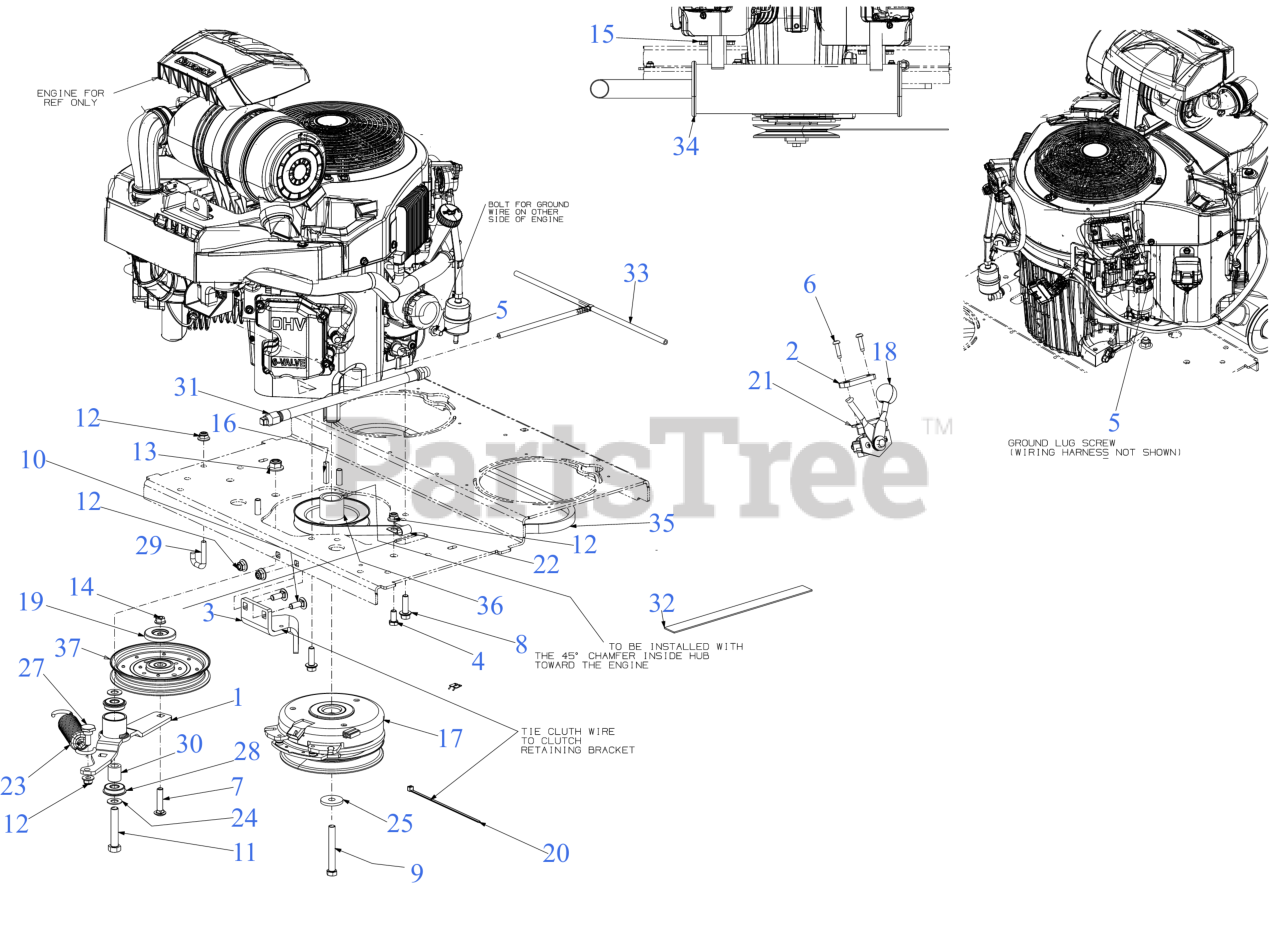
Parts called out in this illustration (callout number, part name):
1	TRANSMISSION IDLER BRACKET
3	CLUTCH RETAINER BRACKET
4	HEX SCREW 3/8-16 x .75
5	SCREW M8 x 1.25 x 16MM GR8.8
6	SCREW 1/4-20 x 1.0
7	CARRIAGE BOLT 3/8-16 x 1.75 GR5
8	SCREW 3/8-16 x 1.25 GR5
9	SCREW 7/16-20 x 3.25 GR5
10	CARRIAGE BOLT 3/8-16 x 1.00 GR5
11	SCREW 1/2-13 x 2.75 GR5
14	HEX LOCK NUT
15	HEX FLANGE NUT
16	SQUARE KEY 1/4 x 1.50
17	ELECTRIC PTO CLUTCH
19	PULLEY CAP
20	7" CABLE TIE
21	ELECTRONIC THROTTLE CONTROL
22	J TYPE CLIP
23	EXTENSION SPRING W/HOOK
24	FLAT WASHER .510 x .995
25	FLAT WASHER .45 x 1.5 x .172 HT
27	SHOULDER SCREW .625 x .302 x 3/8-16
28	ROLLER BEARING .5X1.37X.44
29	ROD SPRING HOOK
30	SPACER 0.51 x 0.88 x 1.00
31	OIL DRAIN HOSE
32	HEAT SHIELD 24"
33	ROLLOVER VENT HOSE ASSEMBLY
34	MUFFLER - KAWASAKI 1000
35	TRANSMISSION BELT
36	DRIVE PULLEY
37	IDLER PULLEY
